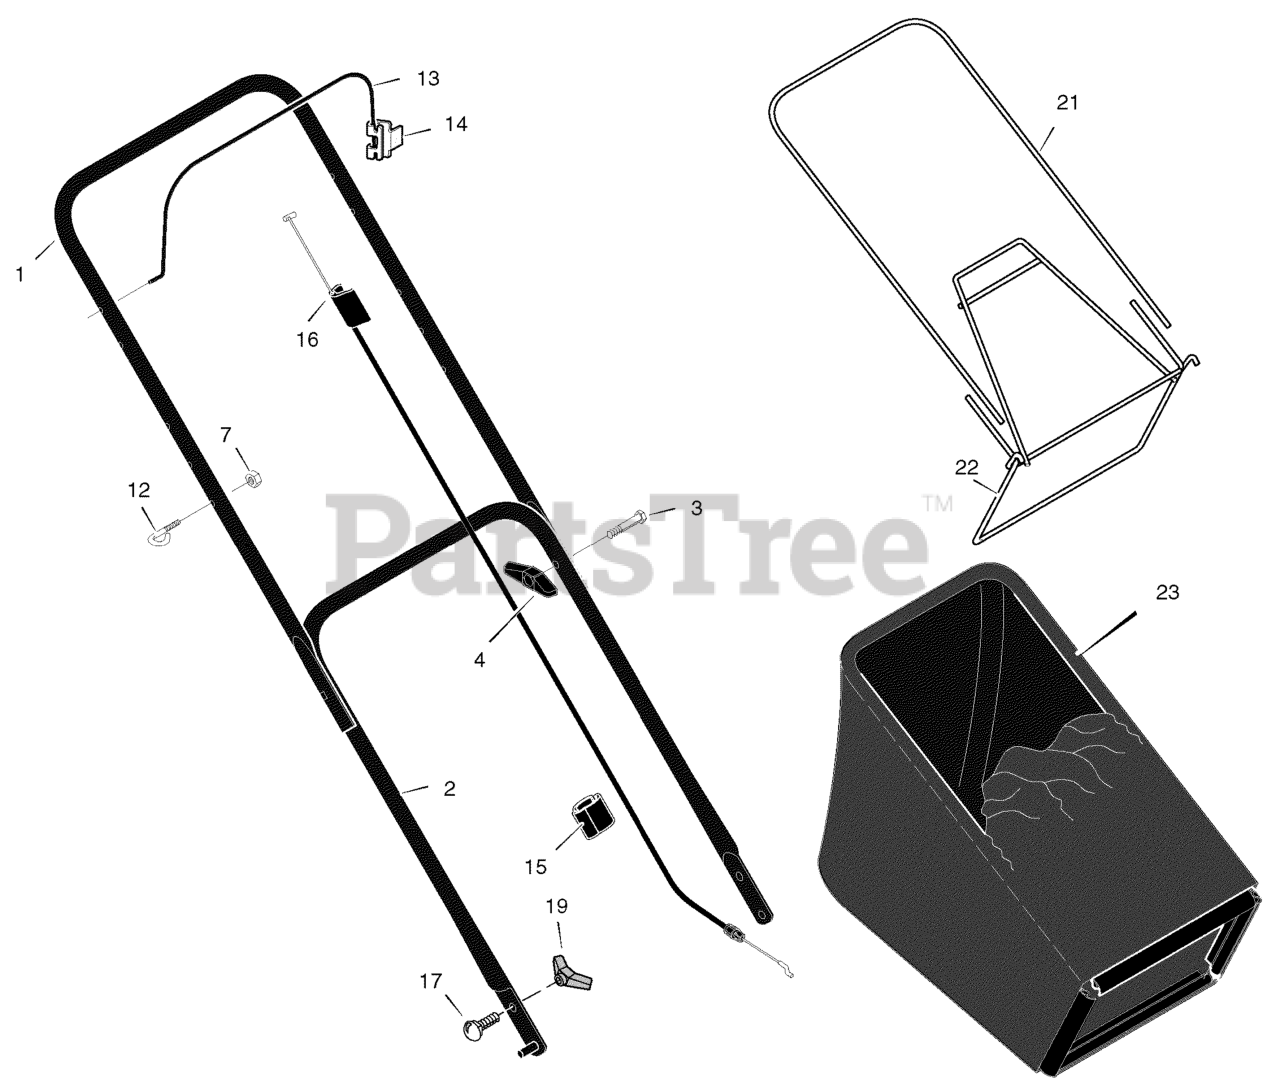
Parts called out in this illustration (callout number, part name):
1	Handle, Upper (Black)
1	Handle, Upper (Gray)
2	Handle, Lower (Black)
2	Handle, Lower (Gray)
4	Knob, Plastic
7	Locknut
12	Guide, Rope
13	Lever, Engine Stop
14	Bracket, Stop Lever
15	Clip, Cable
16	Engine Stop Cable
17	Bolt, Carriage
19	Knob, Plastic
21	Frame, Top
22	Frame Assembly
23	Bag, Cloth
